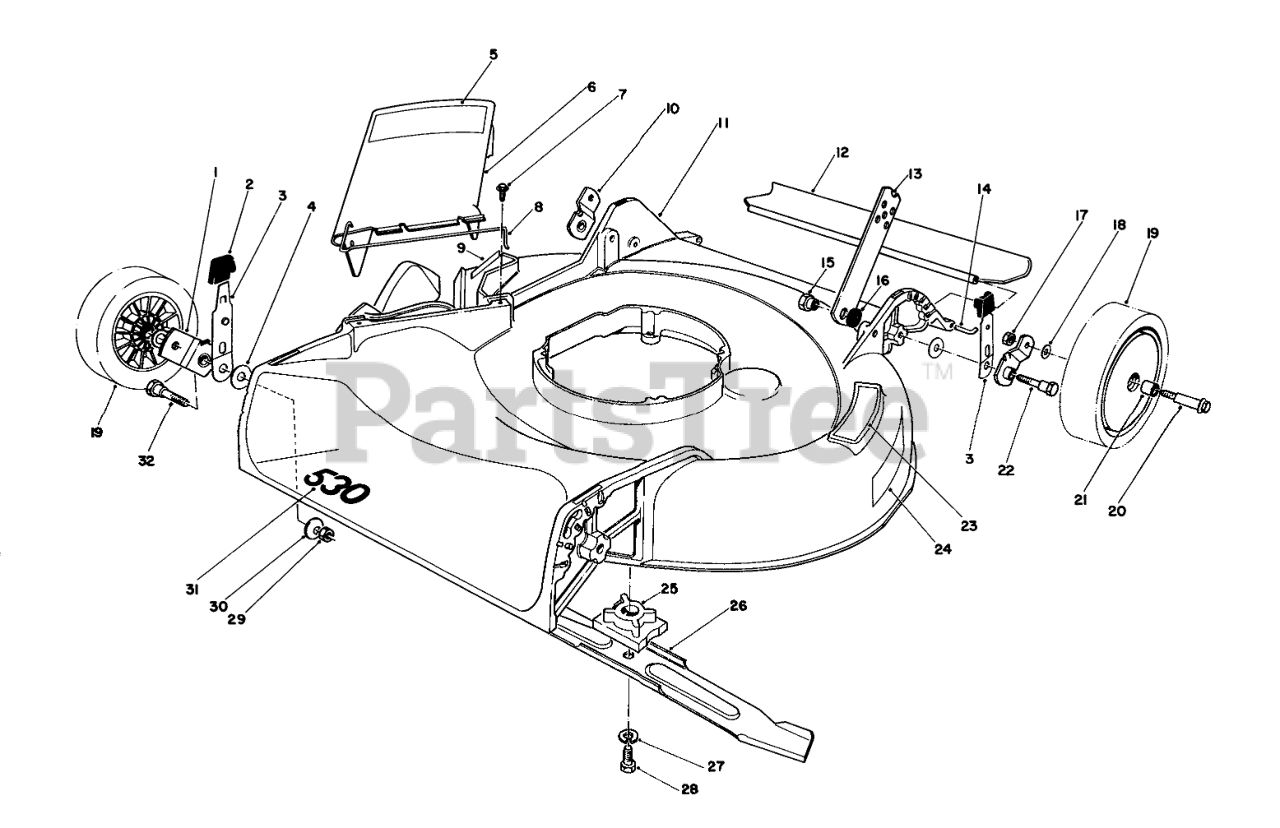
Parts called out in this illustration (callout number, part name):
1	Pivot Arm
2	KNOB-ARM
3	SPRING ARM ASM
4	WASHER-PIVOT
5	Decal-Danger(French)
6	Deflector Assembly (Incl. Ref. #5 8 8)
7	SCREW-HWH
8	SPRING HINGE
9	Decal-Danger
10	Pivot Arm
11	HOUSING/DECAL
12	REAR SAFETY SHIELD 21
13	HANDLE LATCH
14	SHIELD ROD
15	HANDLE PIVOT NUT
16	SPACER
17	NUT-LOCK
18	WASHER
19	Wheel & Tire Assembly (Incl. Ref. #21)
20	WHEEL BOLT
21	BUSHING
22	PIVOT SCREW
23	SPRING
24	Decal-Step
25	BLADE RETAINER
26	Blade
27	WASHER-LOCK
28	SCREW-HH
29	NUT-LOCK, NI
30	WASHER-BELLEVILLE
31	Decal-530
32	PIVOT SCREW
